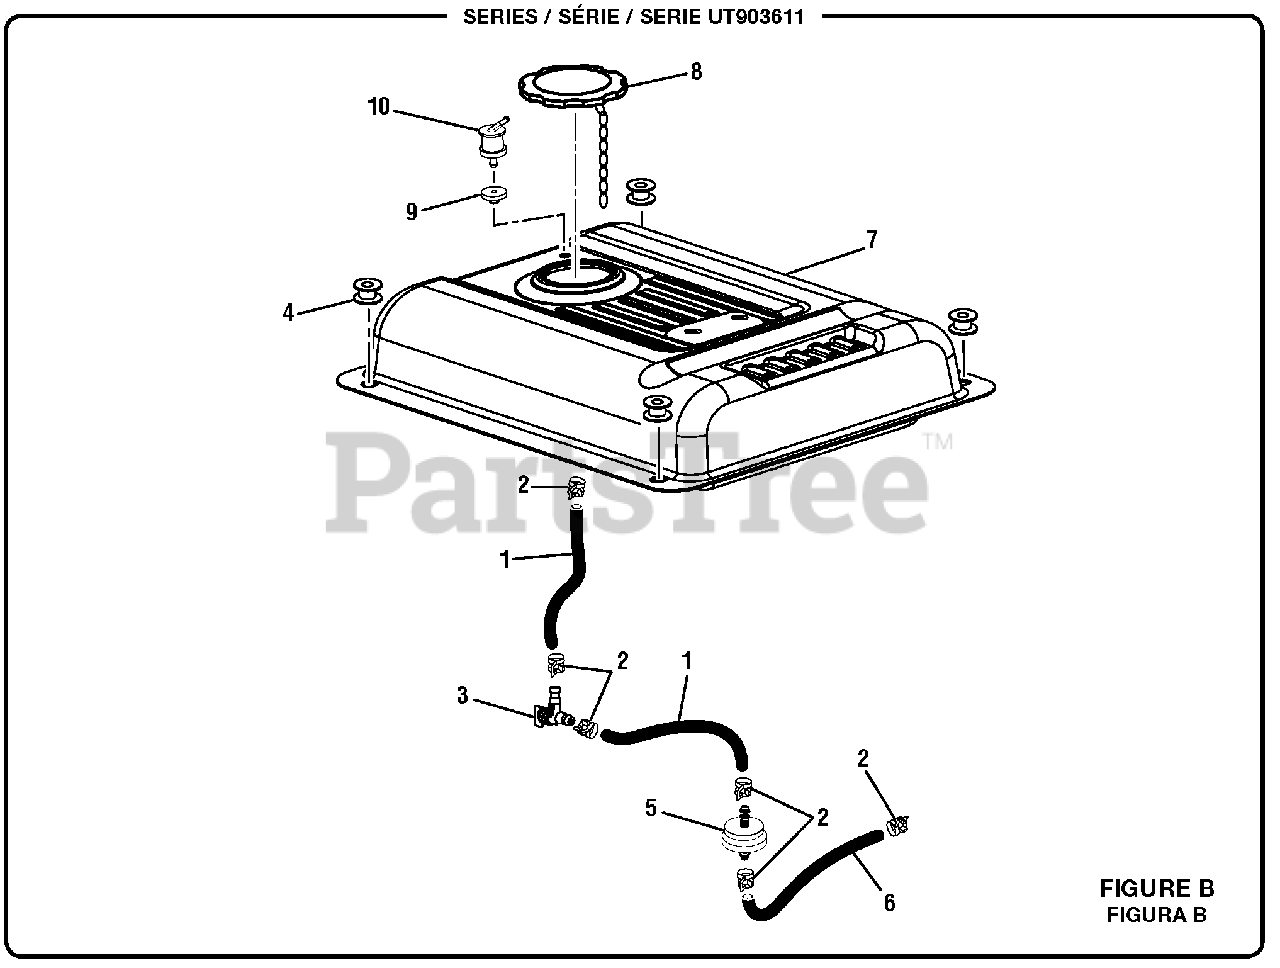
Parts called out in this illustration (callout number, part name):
1	Fuel Line (On Filter)
2	Fuel Line Clamp
3	Fuel Shut Off Valve
4	Bushing w/Insert
5	Fuel Filter
6	Fuel Line
7	Fuel Tank
9	Check Valve Bushing
10	Check Valve
